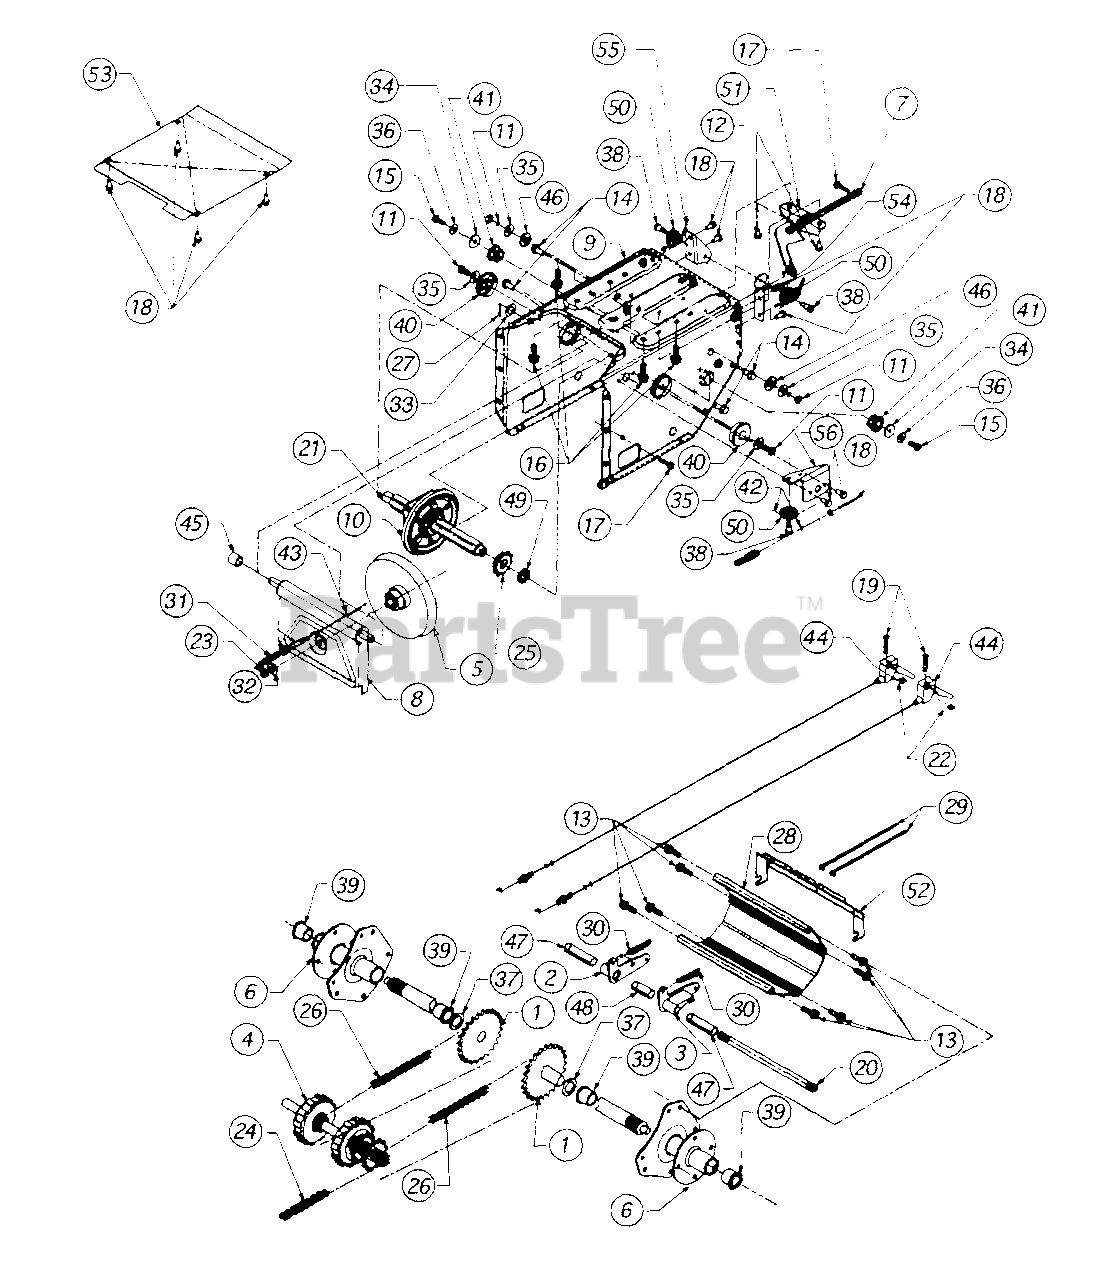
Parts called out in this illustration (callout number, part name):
1	Axle Assembly
2	Dog Assembly - R.H.
3	Dog Assembly - L.H.
4	Shaft Assembly
5	Disc Assembly
10	Wheel Assembly Friction
11	Screw
12	Screw
13	Screw
14	Screw
15	Screw
17	Screw
18	Screw
19	Screw
20	Actuator Shaft
21	Drive Shaft
22	Flange Nut
23	Jam Nut
24	Chain - 1/2 pitch x 30 links
25	Sprocket - 10 tooth
26	#420 Chain - 32 Links
27	Pin Cotter
28	Housing Track
29	Cable Tie
30	Spring
31	Spring
32	Bell Washer
33	Flat Washer
34	Flat Washer
35	Bell Washer
36	Bell Washer
37	Flat Washer
38	Shoulder Screw
39	Flange Bearing
40	Ball Bearing
41	Hex Flange Bearing
42	Cable - Auger Clutch
43	Cable - Drive Clutch
44	Cable with Trigger Lever
45	Spacer
46	Shoulder Spacer
47	Split Spacer
48	Split Spacer
49	Spacer
50	Roller - Cable
53	Cover - Frame
54	Bracket - Guide
55	Bracket - Guide
56	Bracket - Guide
